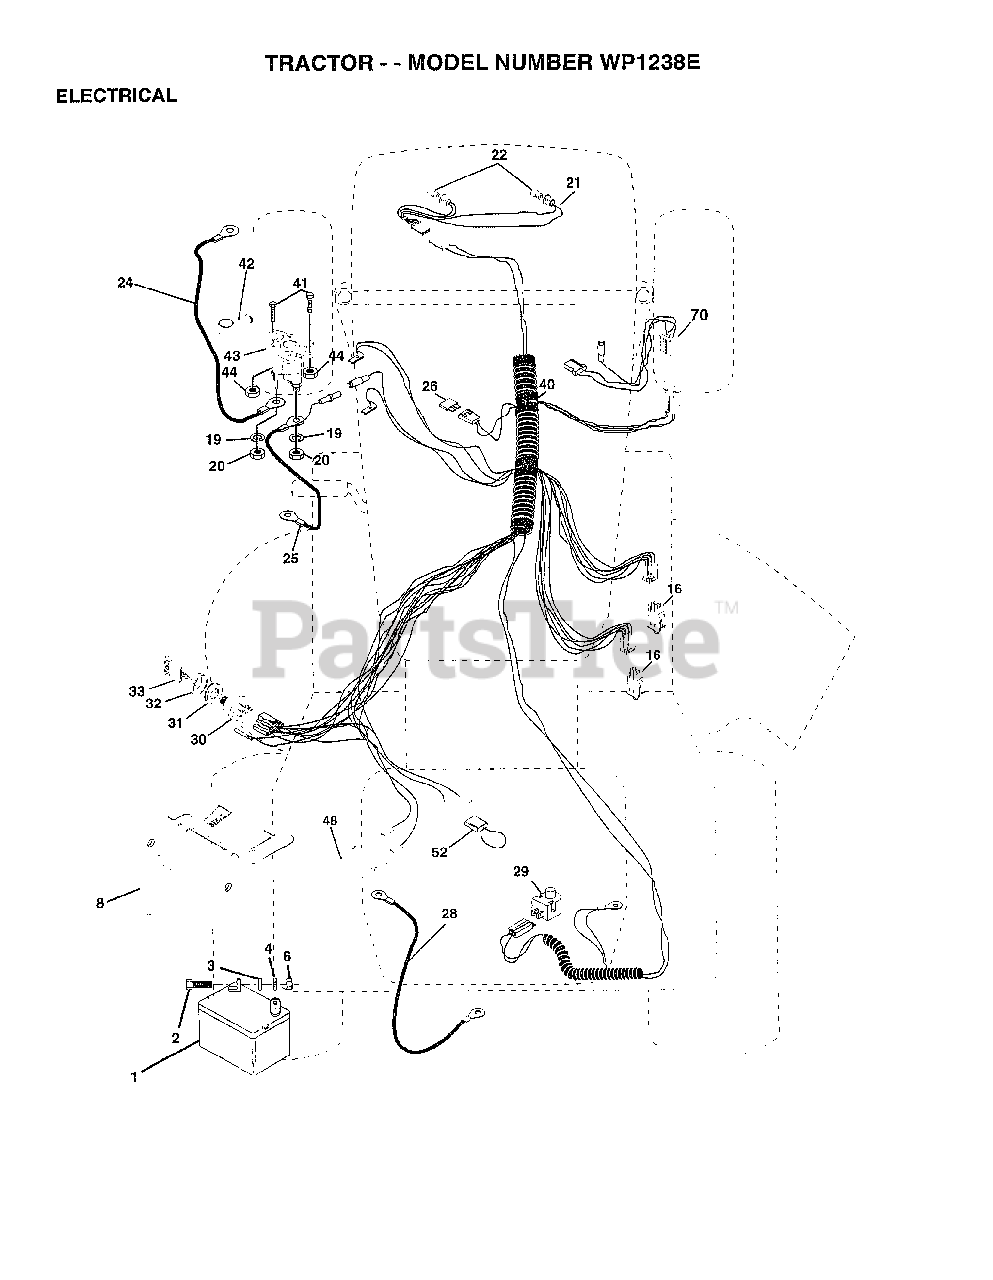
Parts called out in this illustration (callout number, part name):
3	WASHER
4	LOCKWASHER
8	"CASE,BATTERY.MECH"
16	SWITCH INTERLOCK
20	NUT
21	"HARNESS,LIGHT SOC"
22	HEADLAMP BULB
24	"CABLE T, BATTERY"
25	CABLE.BTRY.6GA.RD
26	FUSE HYT
28	CABLE T
29	SWITCH SEAT
30	SWITCH IGN 4POS
31	NUT IGNITION
32	COVER KEY SWITCH
33	KEY
40	HARNESS-IGNITION
41	BOLT HXHD FIN
44	NUT HXKEP 1/4X20
48	ADAPTER AMMETER
52	PROTECTION LOOP
70	HARNESS ENG DUAL
